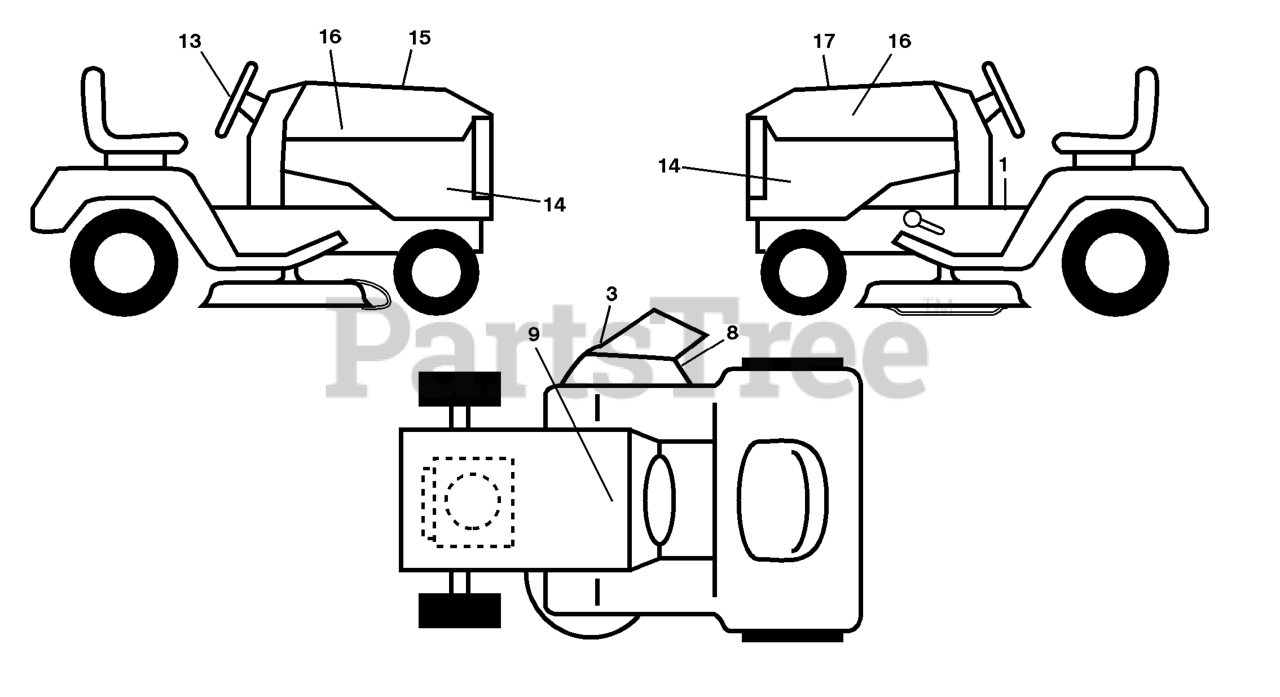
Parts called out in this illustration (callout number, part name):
1	DECAL.FENDER.WARNING.ENG
3	DECAL.WARN.KEEP.HAND.AWAY
8	DECAL V BELT SCHEMATIC
9	DECAL BTRY SYMBOLS
13	DECAL.WHEEL.STRG.LGN.H
14	DECAL.PNL.SD.YTH1542XPT
15	DECAL HOOD CUST. RESP.
16	DECAL.HOOD.LOGO.HUSQVARNA
17	DECAL.RPL.YTH1542XPT.2006
17	DECAL.BYPASS.FENDER.CRD.LT.YT
17	PAD.FOOTREST.LH.HUSQ.T
17	PAD.FTRST.RH.PCH.HUSQ.
17	Manual, Owner's
